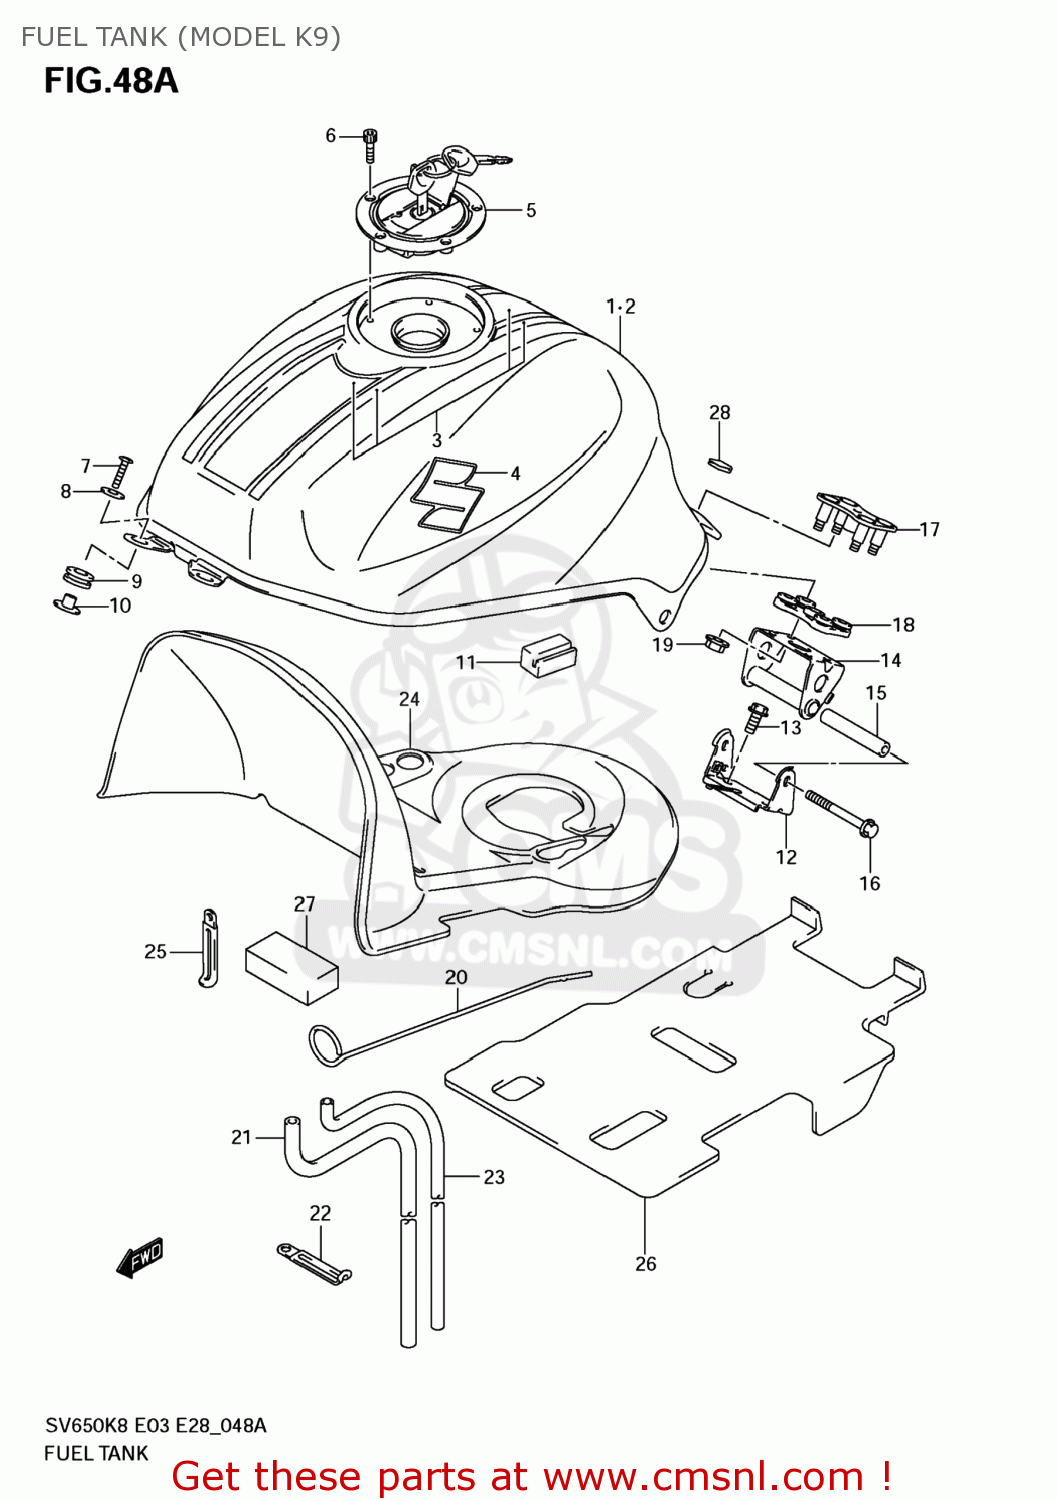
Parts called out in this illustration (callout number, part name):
1	TANK ASSY,FUEL(GRAY)
2	TANK ASSY,FUEL(BLUE)
3	STRIPING.TANK
4	EMBLEM,S
5	CAP SET,FUEL TANK
6	BOLT(5X20)
7	SCREW(6X25)
8	WASHER(6.5X22X1.6)
9	CUSHION,FUEL TANK FR
10	SPACER,FUEL TANK FR
11	CUSHION,FUEL TANK SIDE
12	BRACKET,FUEL TANK NO.2
13	BOLT
14	BRACKET,FUEL TANK NO.1
15	SPACER,FUEL TANK RR
16	BOLT(6X100)
17	BRACKET,FUEL TANK RR UP
18	CUSHION,FUEL TANK RR
19	NUT
20	STAY,FUEL TANK
21	HOSE,WATER DRAIN
22	CLAMP(L:80)
23	HOSE,FUEL TANK BREATHER
24	SHIELD,FUEL TANK HEAT
25	CLAMP(L:80)
26	SHEET,HEAT SHIELD RUBBER
27	CUSHION,FUEL TANK
28	MOLDING
